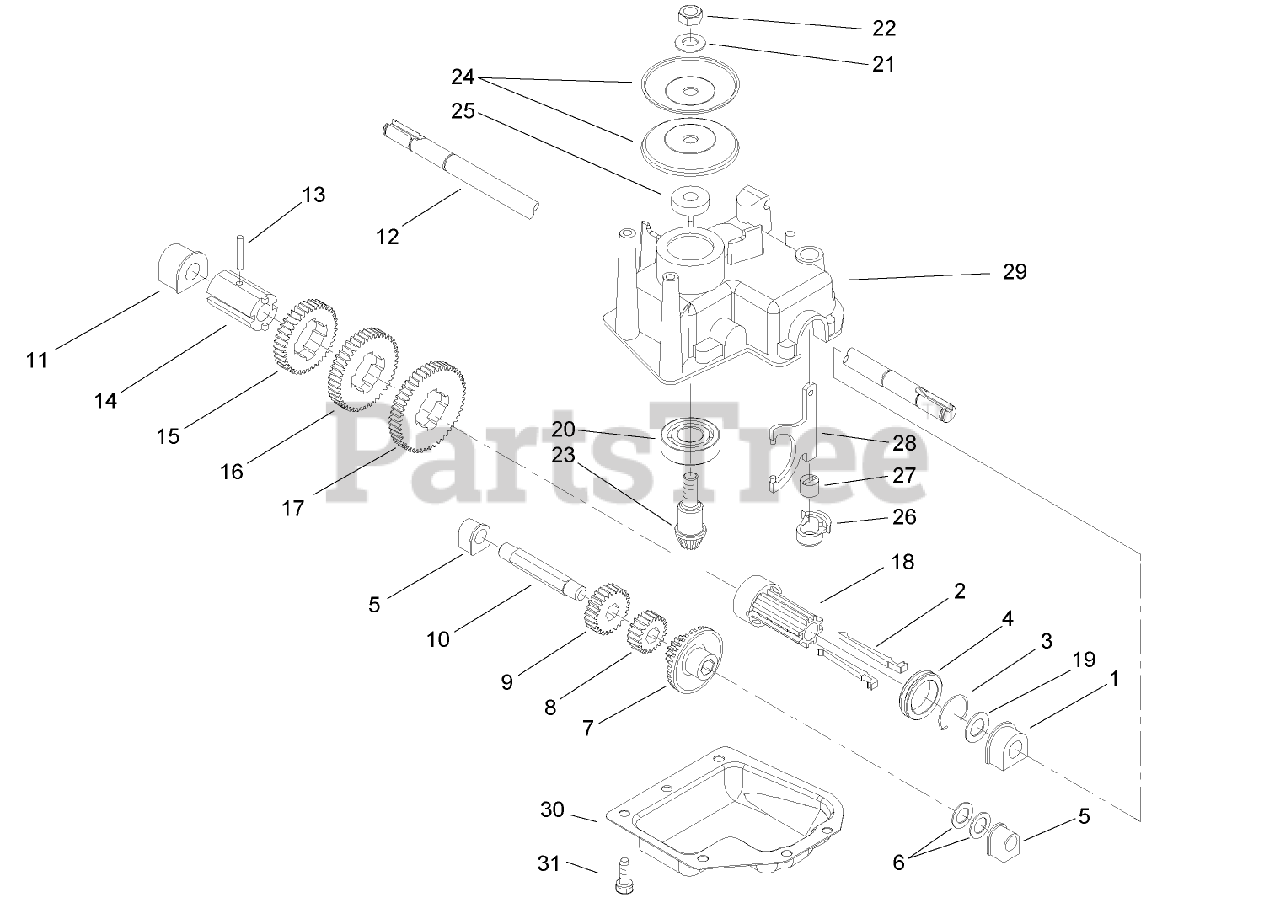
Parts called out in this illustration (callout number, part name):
1	BUSHING-OUTPUT
2	KEY-SHIFT
3	CLIP-SPRING
4	COLLAR-SHIFT
5	BUSHING
6	WASHER-THRUST
7	GEAR-15T SPUR, 37T BEVEL
8	PINION-20T
9	PINION-25T
10	SHAFT-INTERMEDIATE
11	BUSHING
12	SHAFT-OUTPUT
13	PIN-GROOVE
14	SLEEVE-GEAR
15	GEAR-39T
16	GEAR-44T
17	GEAR-49T
18	SLEEVE-KEY, SHIFT
19	WASHER-PLAIN
20	BEARING-BALL
21	WASHER-FLAT
22	NUT-HEX
23	PINION
24	PULLEY-HALF
25	SPACER
26	RETAINER-FORK, SHIFT
27	BUSHING-YOKE
28	YOKE-SHIFT
29	CASE-GEAR, UPPER
30	COVER-CASE, GEAR
31	SCREW-HWHTF
